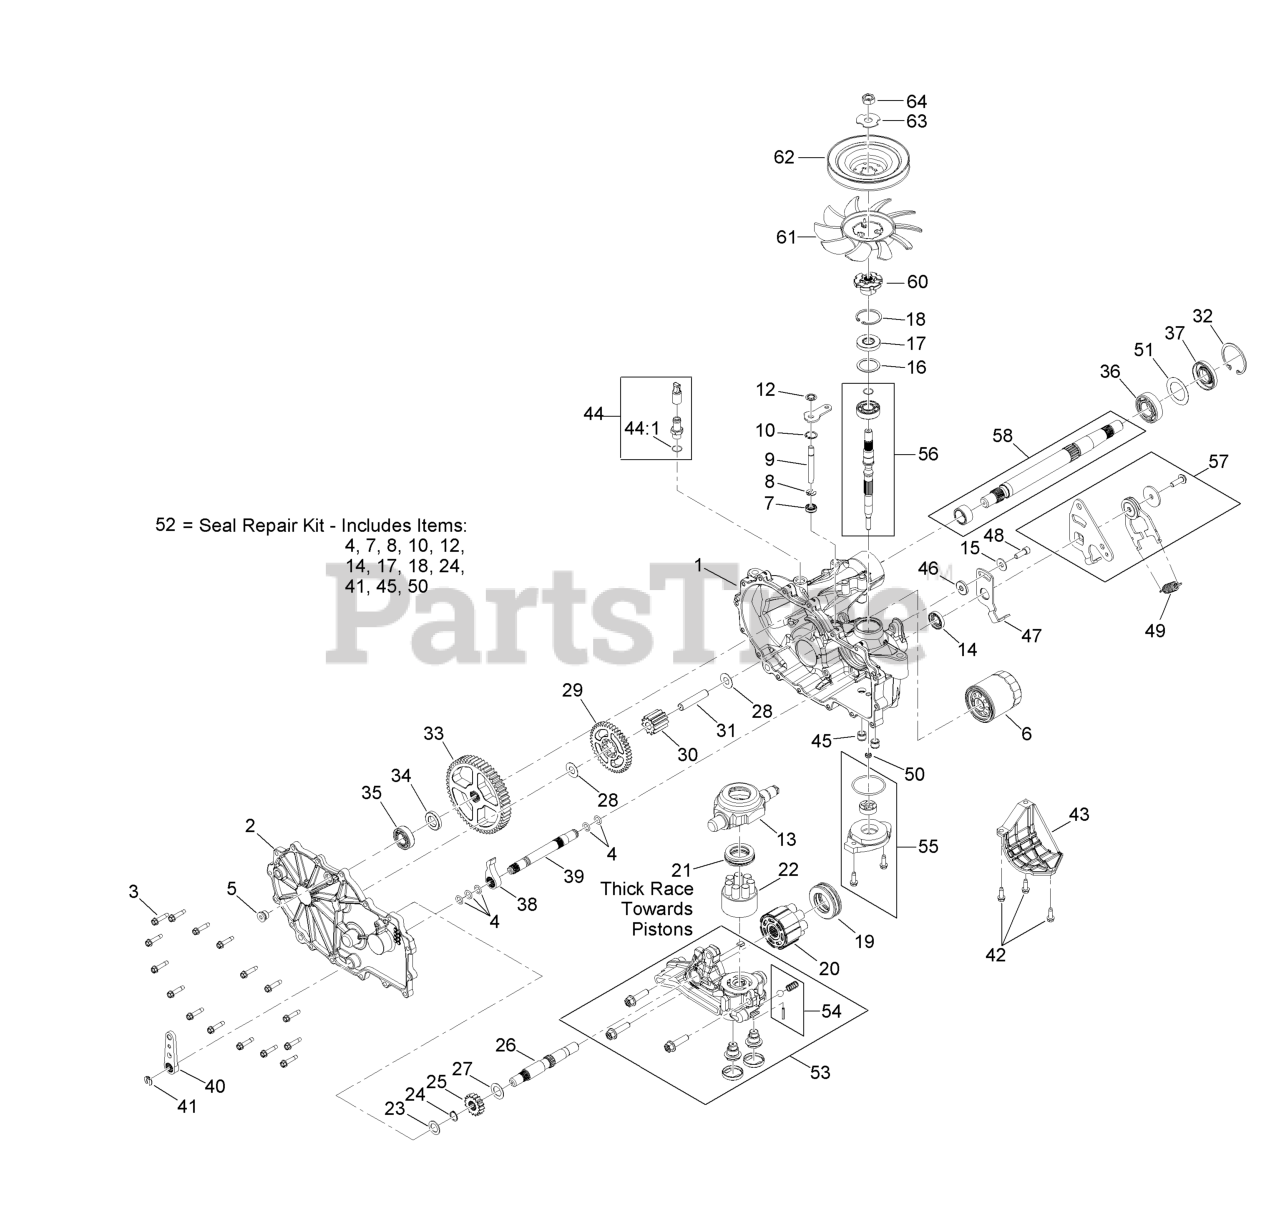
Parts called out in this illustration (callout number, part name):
1	LH Main Housing Kit
2	LH Side Cover Kit
3	Screw-HHF
5	Plug-Straight
6	Filter-Hydraulic
7	Seal-Lip
8	Ring-Retaining, External
9	Rod-Bypass
10	Ring-Retaining, Internal
12	Ring-Retaining, External
13	Swashplate-Trunnion
14	Seal-Lip
17	Seal-Lip
18	Ring-Retaining
19	Bearing-Thrust
20	Motor Cylinder Block Kit
21	Bearing-Thrust
22	Pump Block ASM
23	Washer-Flat
24	Ring-Retaining
25	Gear-16T
26	Shaft-Motor
29	Gear-43T
30	Gear-11T
31	Pin-Jackshaft
32	Ring-Retaining
33	Gear-54T
35	Bearing-Ball
36	Bearing-Ball
38	Pawl-Brake
39	Shaft-Brake, Inboard
40	Handle-Brake
41	Ring-Retaining, EXT
43	Guard-Filter, LH
44	Adapter-Straight
44:1	O-Ring
45	Tube-Connecting
47	Arm-Neutral, Left
48	Screw-Sh
49	Spring-Extension
50	Seal-Gerotor
52	Seal Kit
53	LH Center Section Charge Kit
54	Charge Relief Kit
55	Charge Kit
56	Input Shaft Kit
57	Control Arm Kit
58	Axle Shaft Kit
60	Hub-Pulley
63	Washer-Slotted
